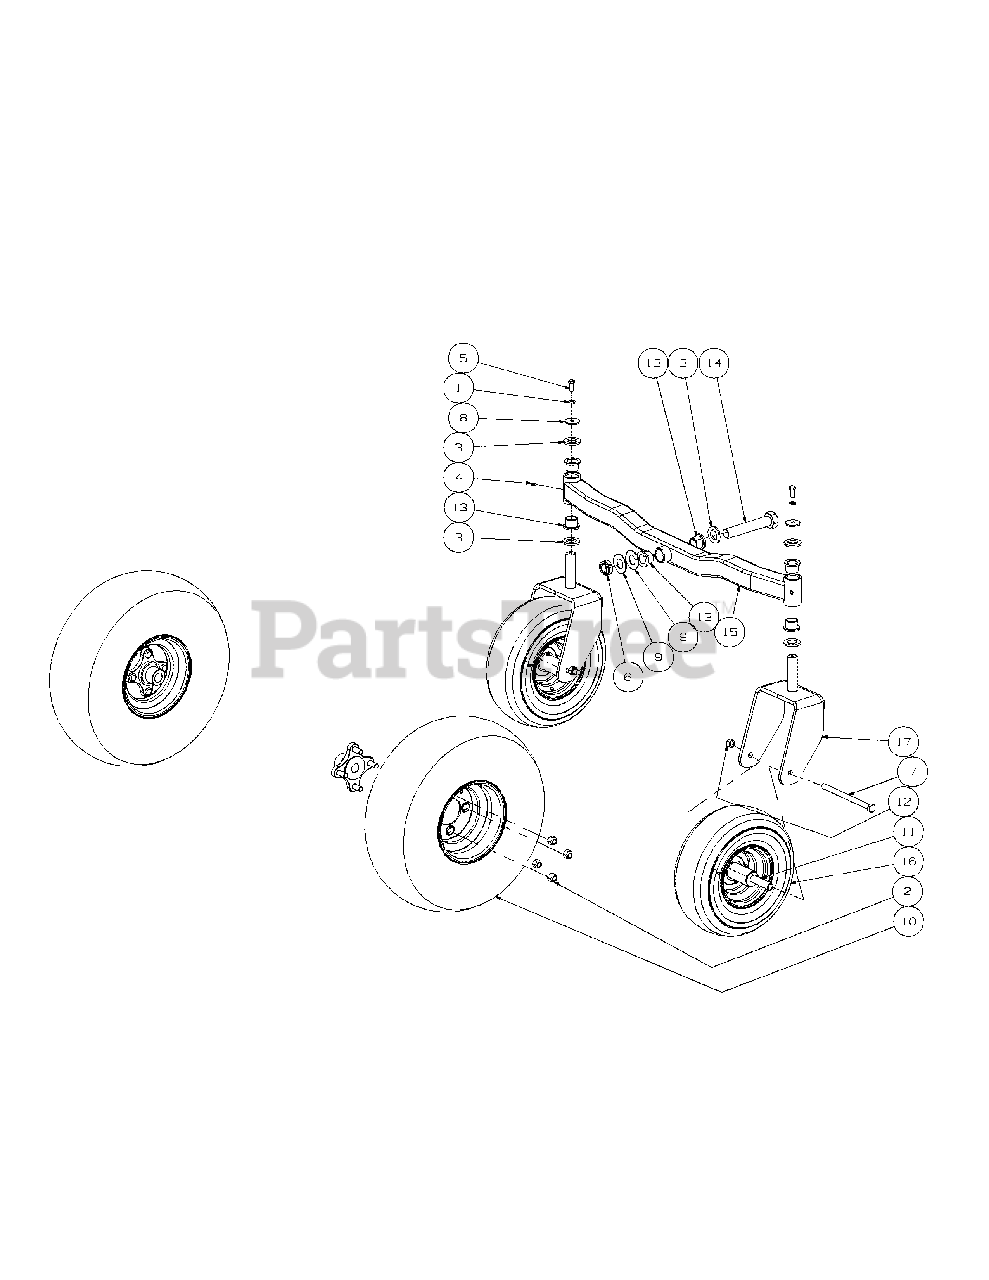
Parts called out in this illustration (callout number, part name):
1	Lock Washer, 3/8 Zinc
2	Lug Nut, 1/2-20
3	Washer Special
4	Grease Fitting, 1/4-28 x 3/16
5	Hex Cap Screw, 3/8-16 x .88
6	Nut Jam, 1.0-14, Nylon Insert
7	Hex Cap Screw, 1/2-20 x 7.50
8	Flat Washer, .390 x 1.5 x .134
9	Flat Washer, 1.00 ID x 2.25 OD x ,075
10	Wheel Assembly, 20 x 8-10 NHS
11	Wheel Spacer
12	Lock Nut, Nylon Insert, 1/2-20
13	Flange Bearing, 1.001 x 1.25
14	Hex Cap Screw, 1-14 x 5.5
15	Front Axle Assembly
16	Wheel Assembly 13 x 5.00-6
17	Castor Wheel Mounting Bracket
